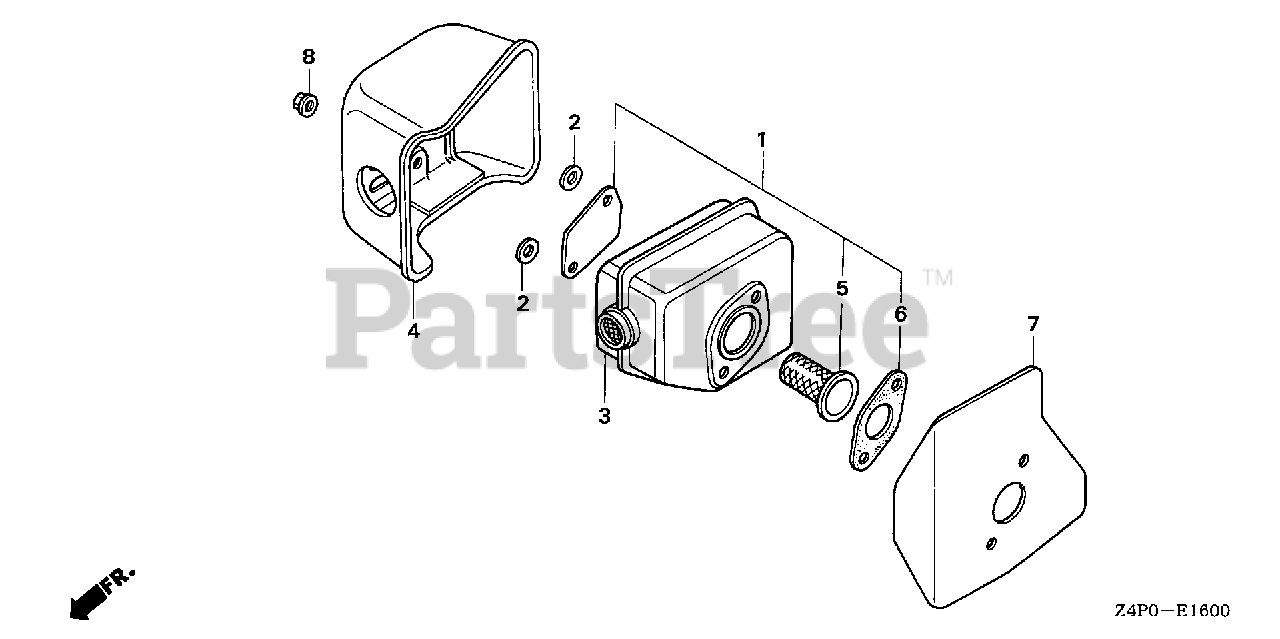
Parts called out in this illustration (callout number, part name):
1	ARRESTER KIT, SPARK
2	GASKET, PROTECTOR
4	PROTECTOR, MUFFLER
5	ARRESTER KIT, SPARK
6	GASKET, MUFFLER
7	GASKET, MUFFLER
8	NUT, SELF-LOCK (6MM)
